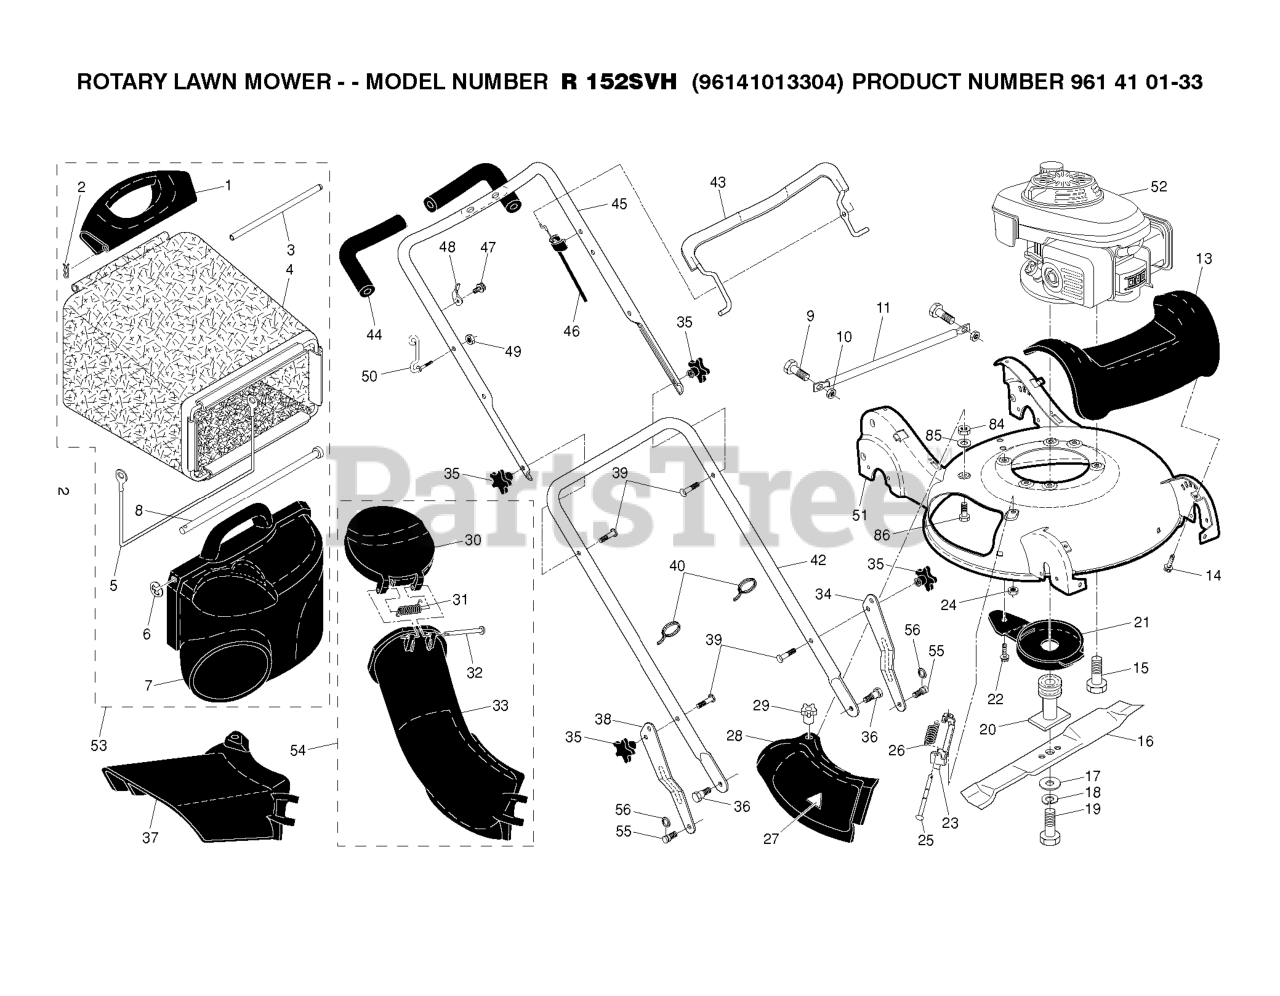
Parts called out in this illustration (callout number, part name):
1	HANDLE.GRASSBAG.REAR.H-GRAY
2	COTTER PIN (3 2)(2 2MC)
3	ROD.REAR.HANDLE.YELLOW
5	FRAME, GRASSBAG
7	DOOR, GRASSBAG
8	ROD, PIVOT
10	LOCKNUT.NYLOC.1/4-20
11	TUBE, REAR SKIRT
13	COVER.FRONT.21.HV.H-GRAY
14	SCREW, HEX WASHER HEAD
15	BOLT 3/8-16X1-1/8
16	Blade, 21"
17	WASHER,HARDEN
18	LOCKWASHER
19	BOLT.HD.HEAD.3/8-24X2.50 (2 2)
20	ADAPTER.BLADE
21	DEBRIS SHEILD
22	SCREW 1/4X20
24	NUT.HEX.FLANGE.1/4
25	ROD.HINGE.1/4"3.82"
26	SPRING.MULCH.DOOR
27	DECAL.INTERNATIONL.CUTFINGER
28	MULCHER DOOR
29	KNOB.MULCH.DOOR
30	CHUTE.DOOR.21.HV.H-GRAY
32	ROD.HINGE.1/4"3.82"
33	DISCHARGE CHUTE PLASTIC
34	ADJUSTMENT BRACKET, LOWER LH
35	KNOB.HANDLE.PLASTIC.STAR.BLACK
36	SCREW.5/16X.680.TRIM.H
37	GUARD.CLIP.ON.21.HV.GRAY
38	BRACKET.ADJ.LOWER.HDL.RT.GREY
39	BOLT, HANDLE 5/16-18X1.75
40	TIE GUIDE
42	HANDLE.LOWER.GREY
43	BAIL.CONTROL.MZR.BS.ORANGE
44	GRIP.HANDLE.FOAM.WIDE.(1 SIDE)
45	HANDLE.ASM.UPPER.W/GRIP
46	CABLE.MZR.50.SNAP-IN
48	BRACKET.UPSTOP.RT
49	NUT
50	GUIDE.ROPE.WALK.MOWER
53	Grassbag Assembly, Complete
54	CHUTE.LOWER.ASM.WALK.MOWER
55	STUD.SHOULDER.T45.BZP
56	E-RING 7/16 RE
84	NUT, HEX
85	LOCKWASHER
86	BOLT.CARRIAGE.1/4-20 X 7/8
